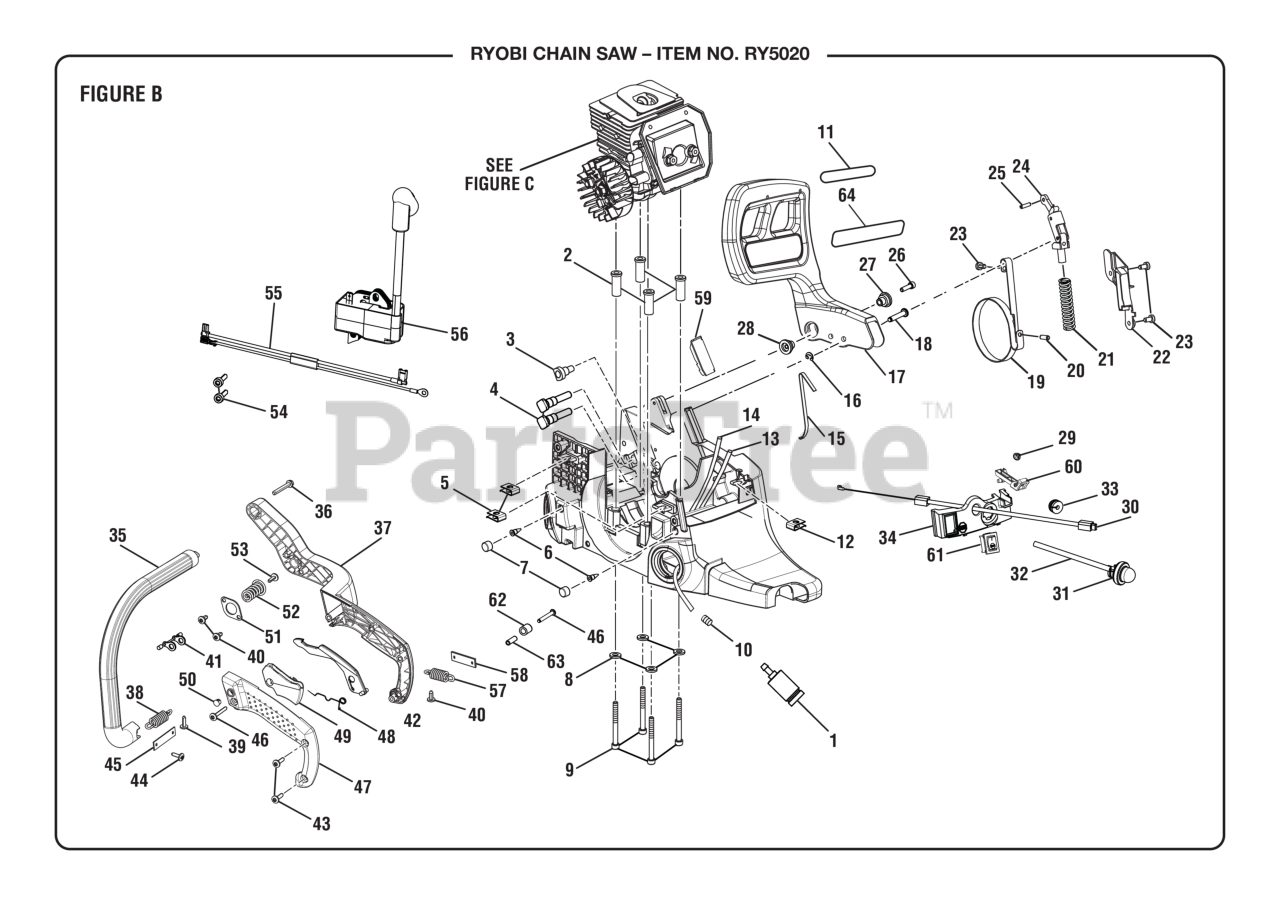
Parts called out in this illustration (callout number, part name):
1	Fuel Filter
2	Spacer Insert
3	GROMMET, OIL OUTLET
4	Control Panel, Black
5	Speed Nut ("U"-type)
6	Front Handle, Black
7	Front Handle, Gray
8	Washer (ID5.8 x OD11.5 x 1.7t)
9	Screw (10-24 X 2 in. Soc. Cap Hd.)
10	Filter Spring Clamp
11	Pull To Release Brake Label
12	Screw (10-14 x 1/2 in.)
13	Inlet Tubing (166 mm)
14	Cupped Washer
15	Screw (10-14 x 3/4 in.)
16	Screw (10-14 Thread Twin Helix)
17	Hand Guard Assembly
18	HAND GUARD ACTUATING PIN
19	Chain Brake Band Kit
20	Roll Pin (Big)
21	SPRING, COMPRESSION
22	Chain Brake Cover
23	Screw (#8-16 x 5/16 in., T25 Torx Pan Hd. T.F.)
24	Chain Brake Link Assembly
25	Spring Pin (Small)
26	Screw (8-32 X 5/8 in. Hex Soc. Hd.)
27	Screw (10-24 x 5/8 in.)
28	Screw (8-32 x 5/8 in.)
29	Ignition Switch Harness
30	THROTTLE CABLE
31	Primer Bulb
32	Primer Tubing (64 mm)
33	Grommet, Wire Harness (Split)
34	Control Panel
35	Front Handle, Black
36	SCREW (12-14 x 1-1/2 in.)
37	Rear Handle, Black
39	Screw, Truss Hd., Plastite (10-14 x 5/8")
40	Screw (10-14 x 1/2 in., Torx Truss Hd. T.F.)
41	Limiter (Upper Isolator Spring)
42	Trigger Release
43	Screws (10-14 x 3/4 in., T25 Torx Pan Hd. T.F.)
44	Screw (10-14 Thread Twin Helix)
45	Spring Retainer
46	SCREW (10-14 x 1-3/8 in.)
47	Handle Cover, Black
48	Torsion Spring
50	PLUG-PLASTIC
51	Isolator Plate
52	Isolator Spring
53	Screw (10-24 X 5/8 in. Torx Hd.)
54	Screw, Thread Form (8-32 x 5/8")
55	Ignition Switch Assembly
56	Ignition Module Assembly
58	Spring Retainer
60	Choke Lever
61	Stop Switch (Momentary Contact)
62	Rubber Bumper
63	Spacer (Spring Screw)
64	Chain Brake Label
